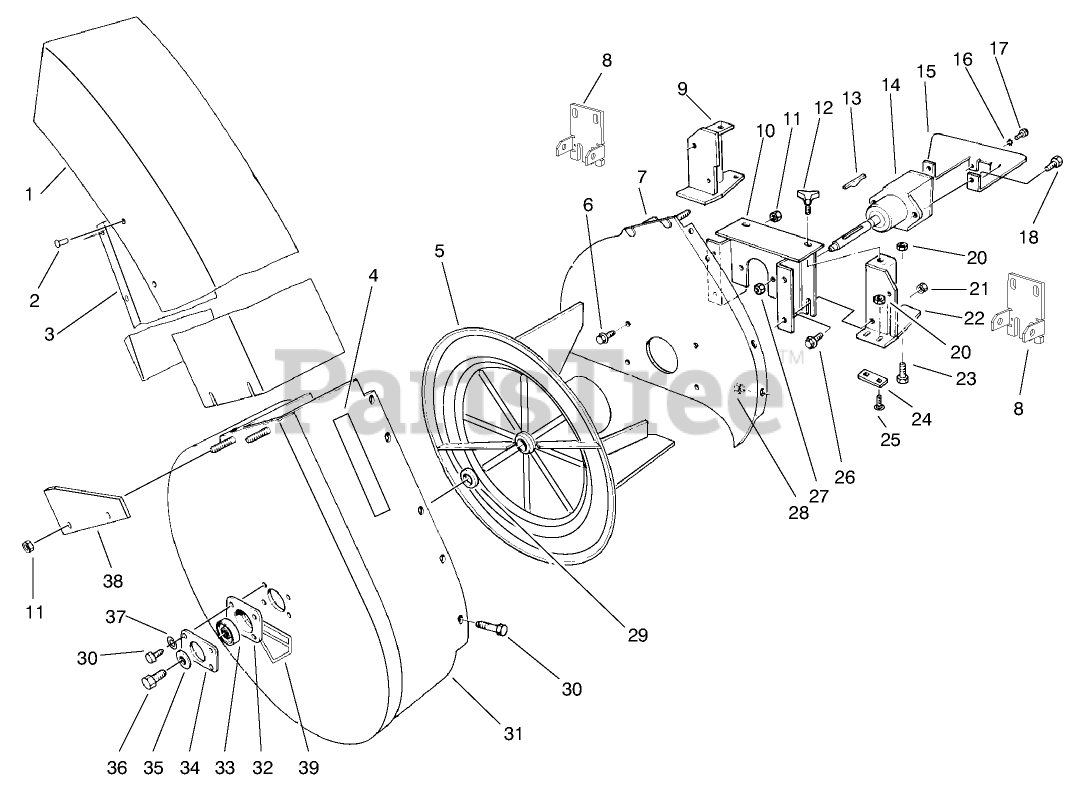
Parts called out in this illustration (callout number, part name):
1	Chute Assembly (Incl. Ref. #2 & 3)
3	Deflector
4	DECAL
5	Impeller
6	SCREW-HHF
7	Mounting Plate
8	Bracket-Pivot
9	LH BRACKET ASM
10	Blower Mount
11	NUT-LOCK, NI
14	Asm-Gear Box
15	Cover-Gear Box
16	WASHER-LOCK, EXT
18	SCREW-HH
20	NUT-LOCK, CONE
21	NUT-JAM
22	RH BRACKET ASM
23	SCREW-HH
24	Plate-Bracket
25	BOLT-CARR
26	SCREW-HHF
27	NUT-LOCK, NI
28	NUT-LOCK, NI
29	SPACER-BEARING
30	SCREW-HH
31	BLOWER HOUSING ASM
32	CUP-BEARING
33	BEARING-BALL
34	Cover-Plate
35	SPACER
36	SCREW-HH, LOCK
37	WASHER-LOCK
38	Bracket
39	DECAL-DANGER
